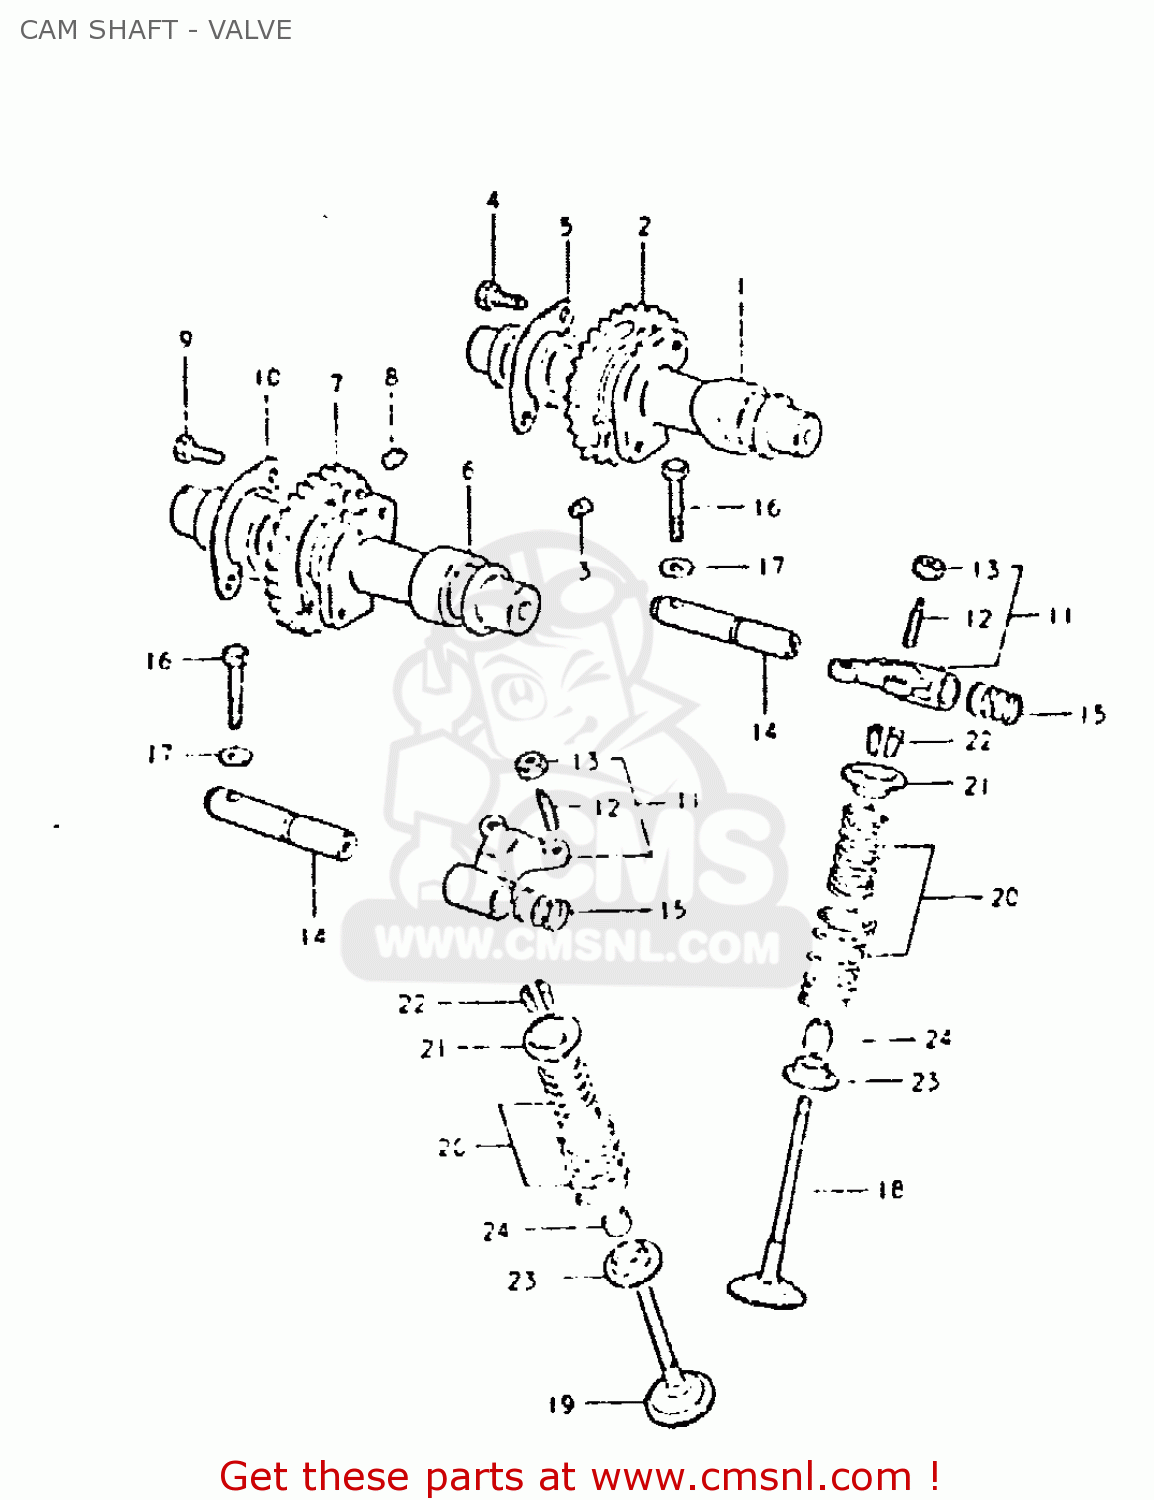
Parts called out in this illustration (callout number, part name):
1	CAM SHAFT, INTAKE
2	SPROCKET (NT:30)
3	PIN,SPROCKET
4	BOLT(6X12.5)
5	WASHER,CAM CHAIN SPROCKET
6	CAMSHAFT,EXHAUST
7	SPROCKET (NT:30)
8	PIN,SPROCKET
9	BOLT(6X12.5)
10	WASHER,CAM CHAIN SPROCKET
11	ARM,VALVE ROCKER
12	SCREW,TAPPET ADJUSTING
13	NUT,ADJUSTING
14	SHAFT,VALVE ROCKER ARM
15	SPRING
16	BOLT
17	WASHER
18	VALVE,INTAKE
19	VALVE,EXHAUST
20	SHIM,TAPPET
21	RETAINER,VALVE SPRING
22	COTTER VALVE
23	SEAT,VALVE SPRING
24	OIL SEAL
